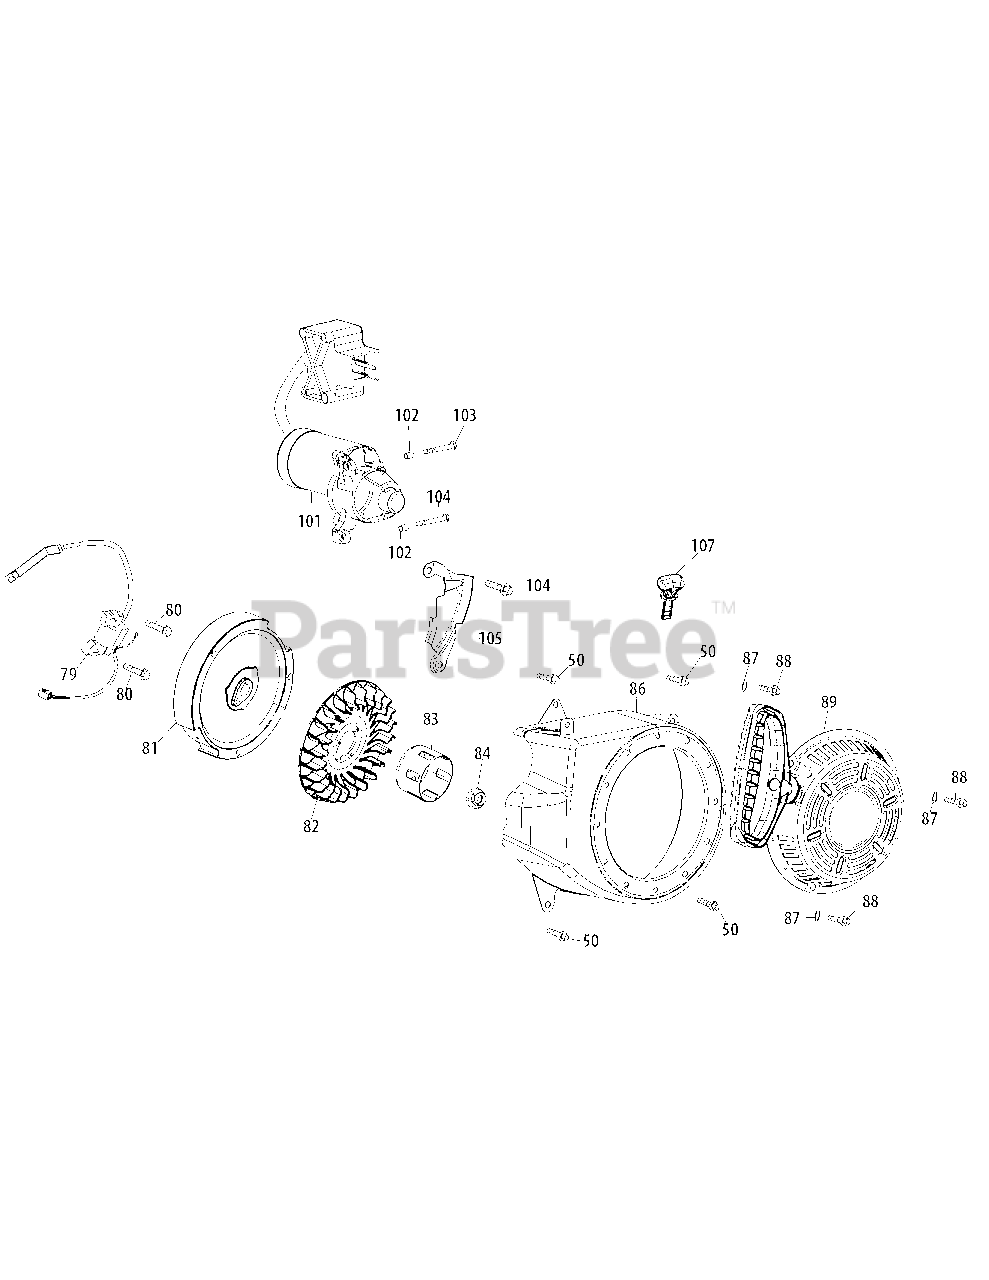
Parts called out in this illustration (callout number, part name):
50	Bolt M6×12
79	Ignition Coil Assembly
80	Bolt M6×25
81	Flywheel
82	Fan, Cooling
83	Pulley, Starter
84	Nut, Special, M14×1.5
86	Blower Housing
87	Gasket 6
88	Bolt M6×10
89	Recoil Starter
89	Recoil Starter Handle
101	Electric Starter
102	Dowel Pin 8×8
103	Bolt M6×32
104	Bolt M6×18
105	Blower Housing Shield
107	Key
107	Key Switch
